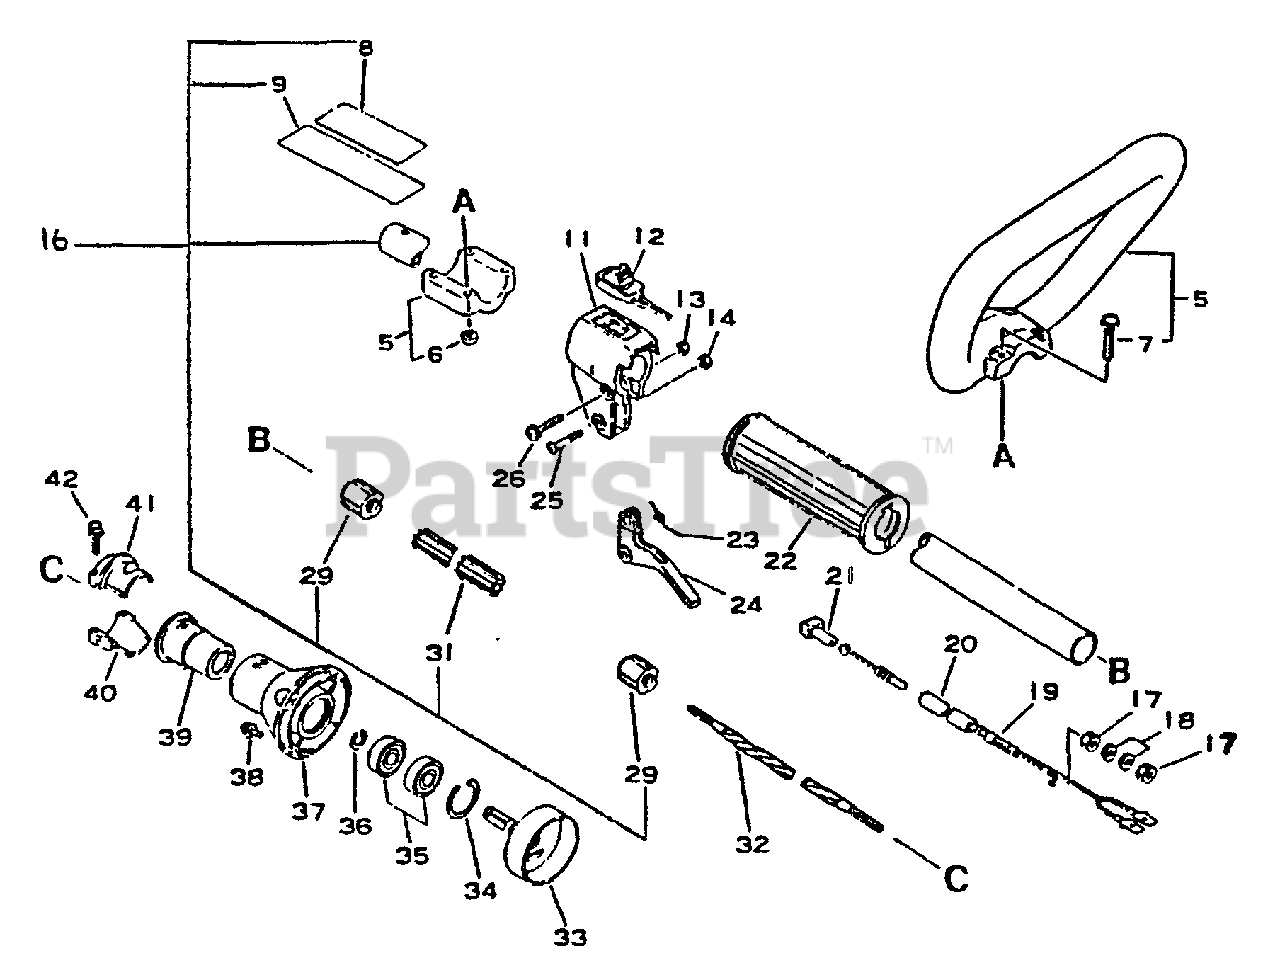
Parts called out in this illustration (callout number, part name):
5	LOOP HANDLE ASSY
6	NUT M5
7	SCREW 5×35
8	LABEL - CAUTION
9	LABEL - CAUTION
11	BRACKET, THROTTLE CONTROL
12	IGNITION SWITCH ASSY
13	NUT M5
14	LOCKNUT - 5
16	MAIN PIPE ASSY
18	WASHER 6.5×11.5×0.8
19	CABLE, THROTTLE
21	GUIDE, CABLE
22	GRIP, HANDLE
23	SPRING, THROTTLE
24	TRIGGER, THROTTLE
26	SCREW 5×30
31	LINER, FLEXIBLE 21.6×1420
32	DRIVESHAFT - FLEXIBLE L= 1522
33	DRUM, CLUTCH
34	RING, SNAP 28
35	BEARING, BALL 6001
36	RING, RETAINING - 12
37	CASE, CLUTCH
38	SCREW 5×16
41	HOLDER, MAIN PIPE - UPPER
42	BOLT - 5×25
